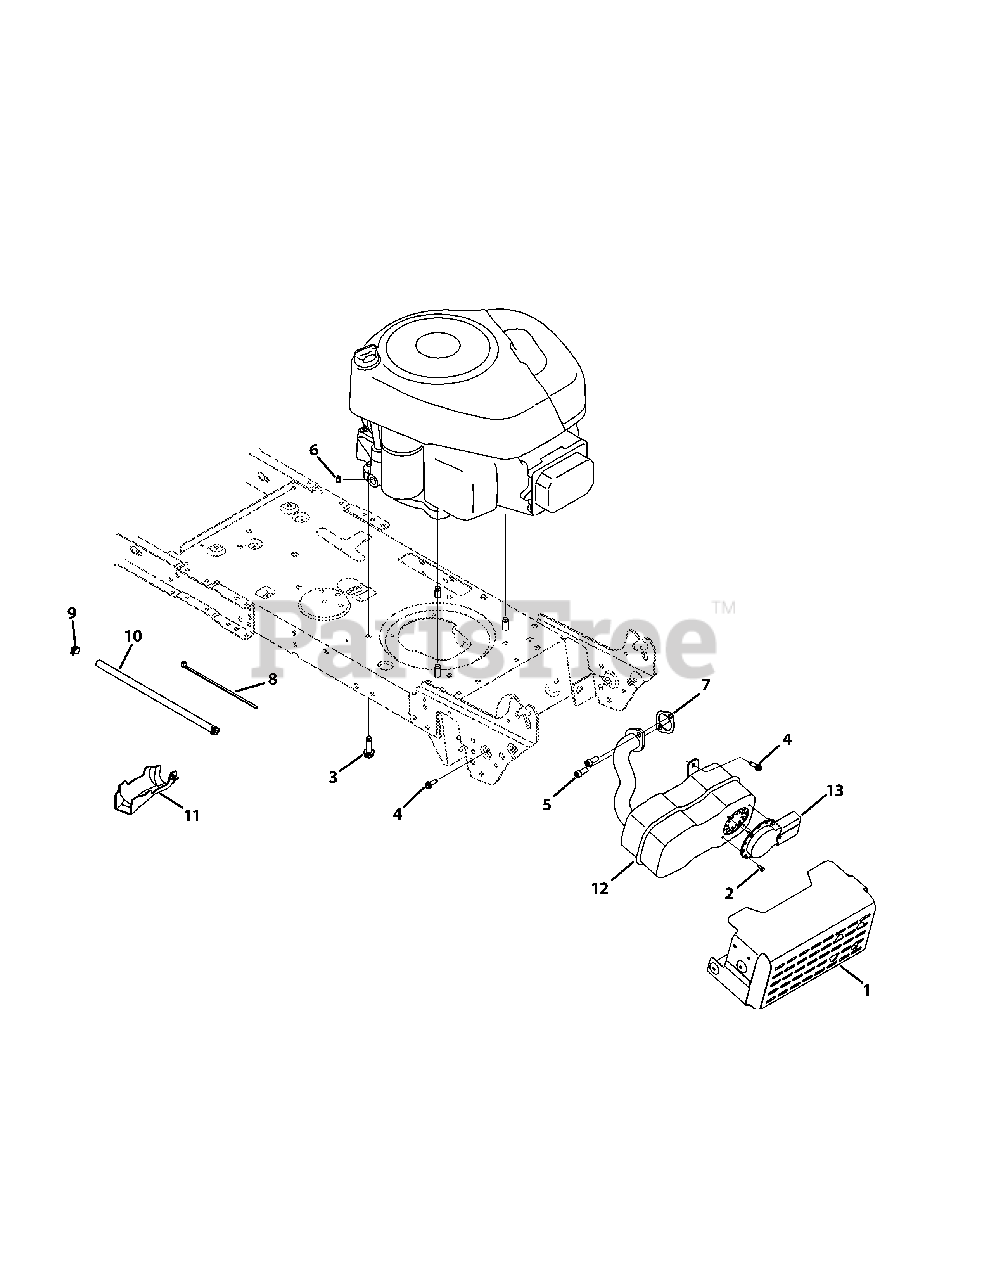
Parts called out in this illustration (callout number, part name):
1	Muffler Shield Assembly with Weld
2	Screw, 8-18 x .500
3	Screw, 3/8-16 x 1.0
4	Screw, 1/4-20 x .750
5	Socket Screw, 5/16-18 x .750
6	Sems Nut, 1/4-20
7	Exhaust Gasket, 10 HP Briggs
8	Cable Tie
9	Clamp Hose, .490 diameter
10	Fuel Hose, Low Permeation
11	Oil Drain Sleeve
12	Muffler, Single Inlet
13	Muffler Deflector Long
